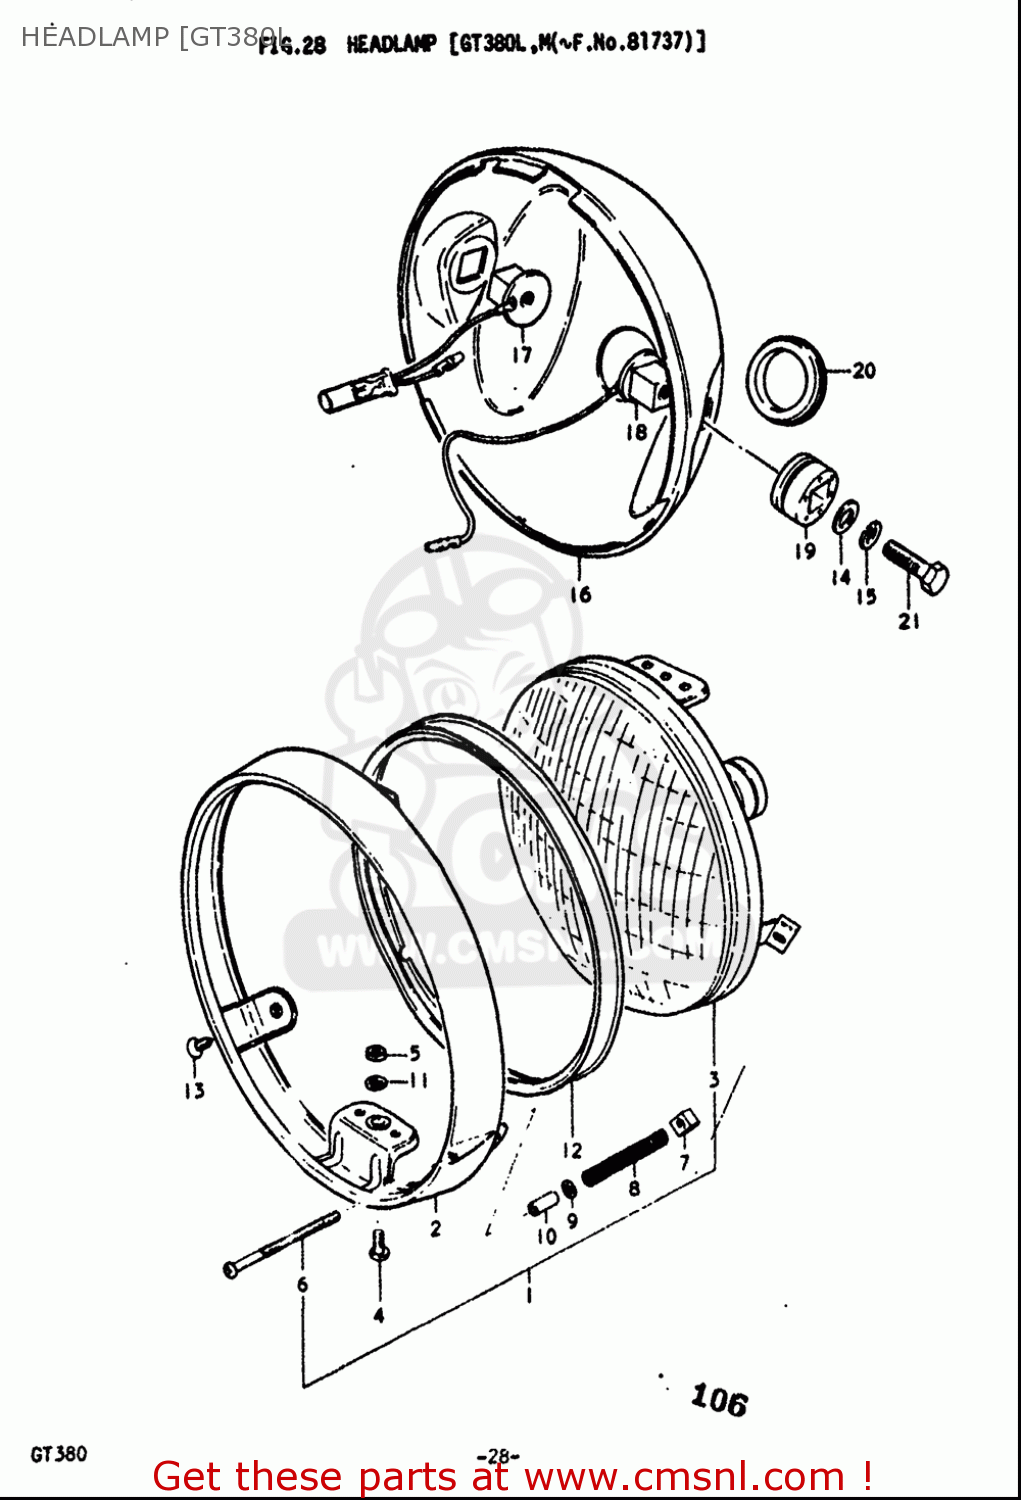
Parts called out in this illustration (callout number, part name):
4	H/LAMP LENS UNIT FITING SCRE
5	NUT
6	SCREW
7	NUT
9	WASHER
11	WASHER,LOCK
12	RETAINER,HEADLAMP
13	SCREW
14	WASHER
15	WASHER,LOCK
16	HOUSING,HEADLAMP
19	CUSHION,HEADLAMP HOUSING
20	GROMMET,HEADLAMP HOUSING
21	BOLT
